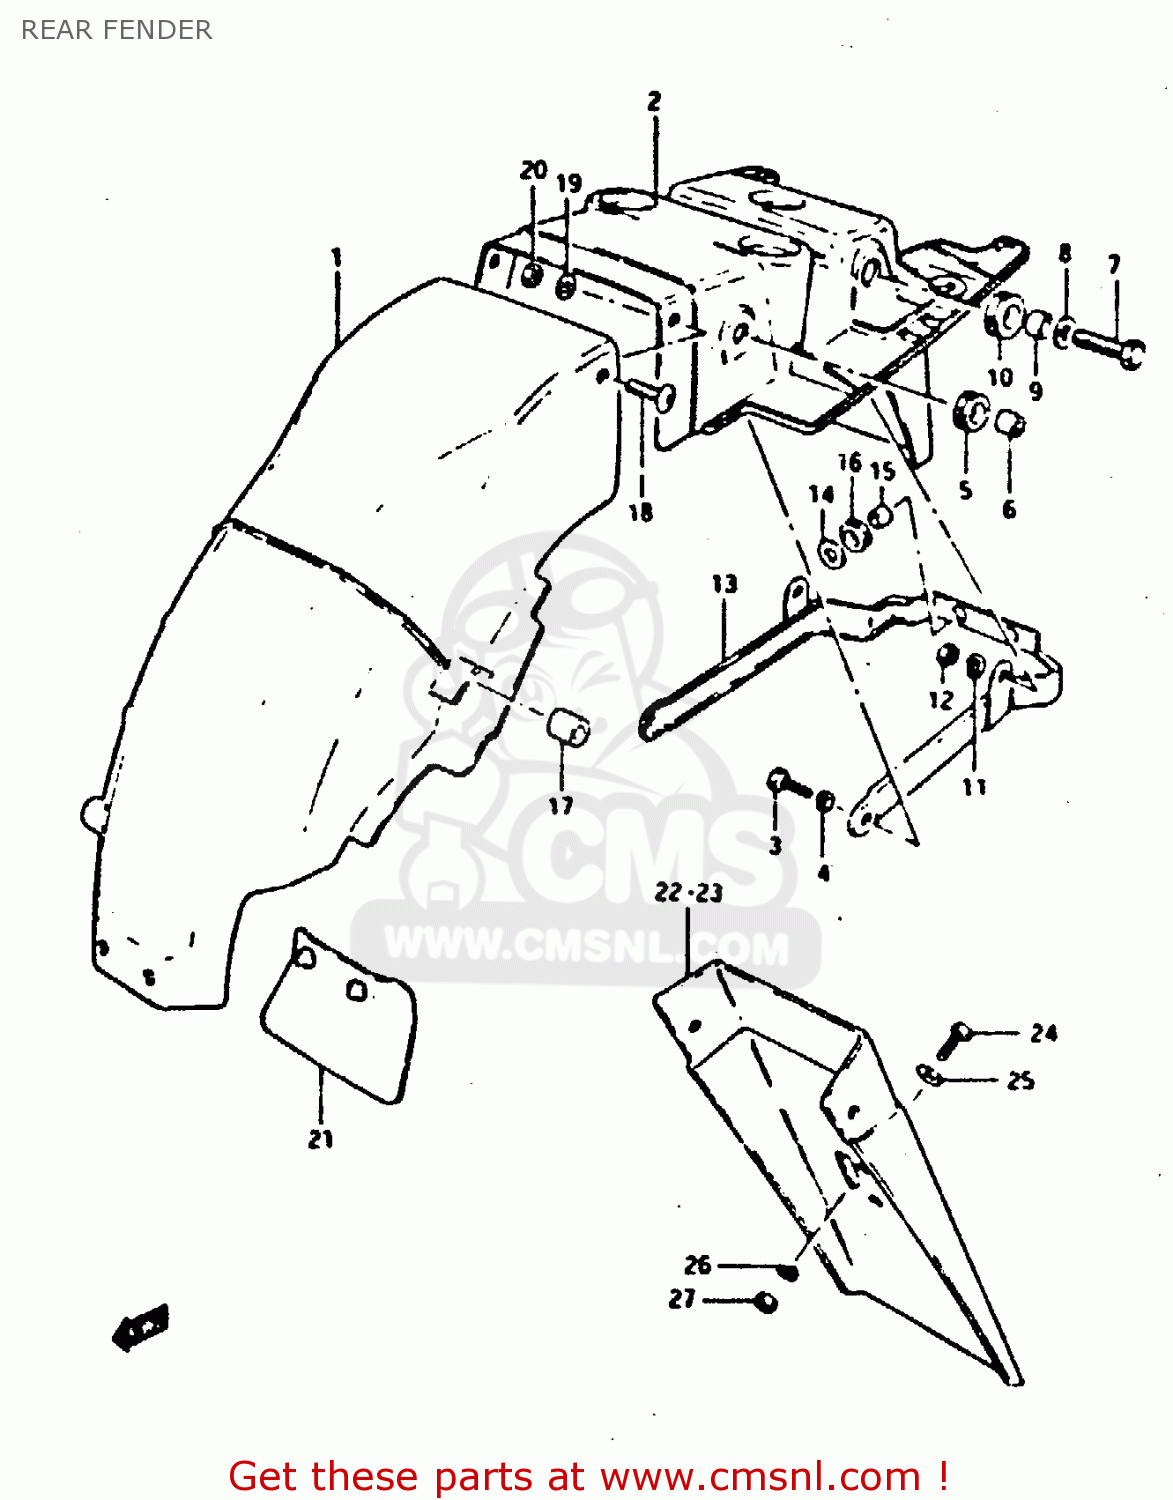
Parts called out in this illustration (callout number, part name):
1	FENDER,REAR
2	BODY,REAR FENDER,REAR
3	BOLT
4	LOCK WASHER
5	CUSHION
6	SPACER(6.1X9X7.5)
7	BOLT (8X30)
8	WASHER
9	SPACER (8.2X12X7.5)
10	CUSHION
11	LOCK WASHER
12	NUT
13	REINFORCEMENT,REAR FENDER
14	WASHER(6,5X22X1.6)
15	SPACER (6.1X9X9)
16	CUSHION
17	CUSHION
18	SCREW
19	WASHER (5.5X16X1.2)
20	NUT
21	GUIDE,RR FENDER MUD
22	EXTENSION, REAR FENDER
23	EXTENSION, REAR FENDER
24	SCREW
25	WASHER(6.5X18X1)
26	LOCK WASHER
27	NUT 6MM
